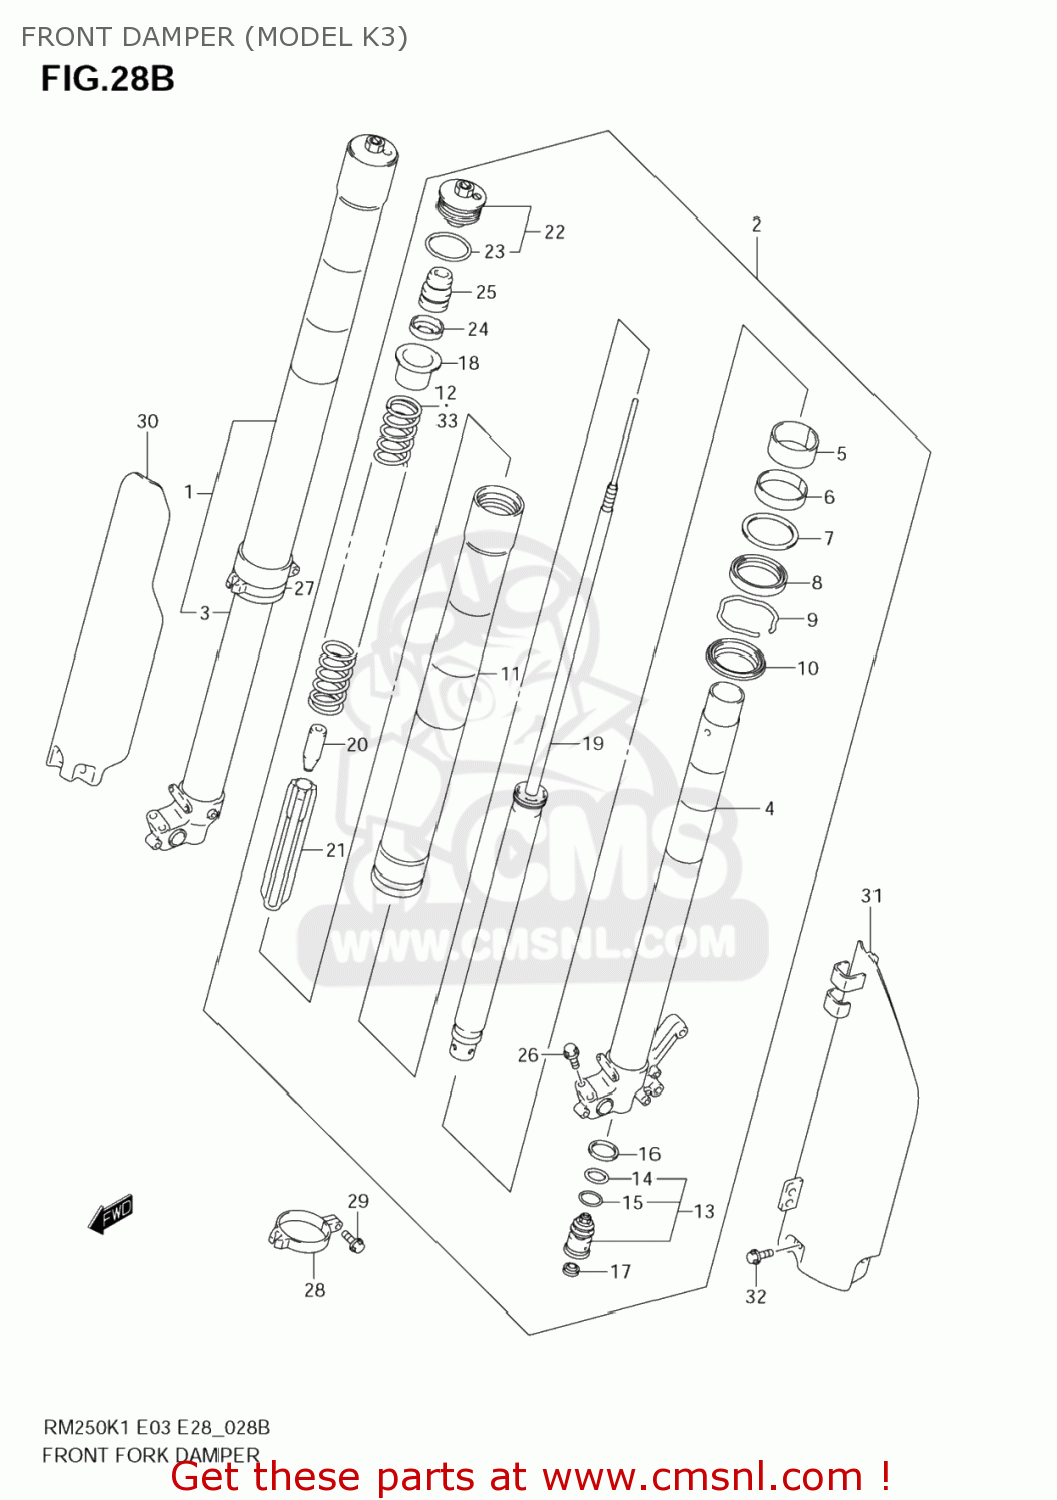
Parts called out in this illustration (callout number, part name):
1	DAMPER ASSY,FR FORK,R
2	DAMPER ASSY,FR FORK,L
3	TUBE,INNER,R
4	TUBE,INNER,L
5	BUSH,SLIDE
6	BUSH,GUIDE
7	WASHER
8	SEAL,OIL
9	RING,STOPPER
10	SEAL,DUST
11	TUBE,OUTER
12	SPRING,FR(K=4.2)
13	VALVE ASSY,BASE
14	O RING
15	O RING
16	PACKING (NAS)
17	CAP,RUBBER
18	SPACER
19	ROD ASSY,PISTON
20	NUT
21	GUIDE,SPRING
22	CAP
23	O RING
24	WASHER
25	RUBBER,CUSHION
26	BOLT
27	GUIDE,PROTECTOR,R
28	GUIDE,PROTECTOR,L
29	BOLT
30	PROTECTOR FORK,R
31	PROTECTOR,FORK,L
32	BOLT(6X10)
33	SPRING,FR(K=4.2)
